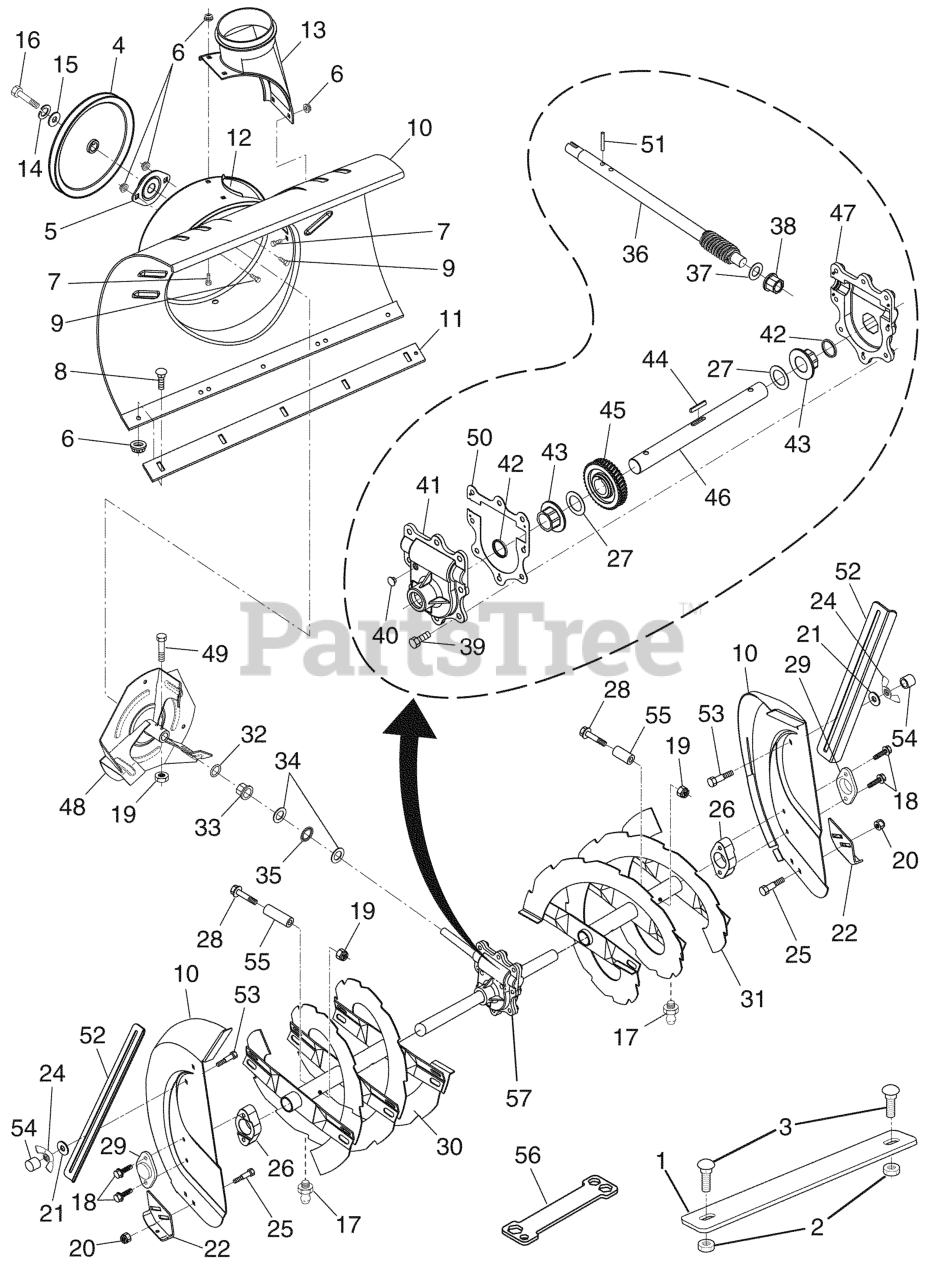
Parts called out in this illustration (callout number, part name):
1	WEIGHT AUGER HOUSING 30
2	NUT.LOCK.5/16-18
3	BOLT.CARRIAGE.5/16-18
4	PULLEY, IMPELLER
5	BEARING FLANGE
6	NUT.FLANGE.5/16
7	BOLT.CARRIAGE.5/16-18X
8	BOLT
9	BOLT, HEX HEAD 5/16-18
10	HOUSING, AUGER
11	BAR, SCRAPER
12	BRACKET, CORNER DISCHARGE
13	BASE DISCHARGE CHUTE
14	WASHER.LOCK.HVY.HLCL.SPR.5/16
15	WASHER, FLAT
16	CAPSCREW.HX.HD.5/16-18X1.00.NY
17	GREASE FITTING
18	SCREW, HEX HD 5/16X1
19	LOCKNUT.NYLOC.1/4-20
20	NUT.FLANGE.5/16
21	WASHER.12021.438X.75X.06.PLS
22	SKID PLATE
24	NUT WING PM
25	BOLT
26	BEARING RETAINER, PLASTIC
27	WASHER TRUST 1"
28	BOLT, SHEAR
29	BEARING.BALL.AUGER.SHAFT
30	AUGER ASSEMBLY, RH
31	AUGER ASSEMBLY, LH
33	BUSHING, FLANGE 3/4
34	WASHER, THRUST 3/4
35	BEARING TRUST 3/4 NTA-1220
36	SHAFT, IMPELLER
37	WASHER, THRUST 5/8
38	FLANGE BUSHING-5/8
39	HEX SCREW-5/16 X 3/4
40	CASE PLUG
41	GEARBOX HOUSING-RH
42	OIL SEAL
43	FLANGE BUSHING-1"
44	KEY, SQUARE 1/4 X .875
45	WORM GEAR
46	AUGER SHAFT
47	HOUSING.GEARBOX.LH(SERVICE)
48	IMPELLER ASSY
49	SCREW.HEX.HD1/4-20X
50	GEARBOX GASKET
51	PIN, ROLL 3/16 X 1-1/8
52	DRIFT CUTTER BAR
53	BOLT
54	STOP.11261.PLASTIC.30X50L.RED
55	SPACER.3943.SLEEVE.250X.47
56	RP WRENCH, SNOWTHROWER
57	GEARBOX.ASSEMBLY.AUGER
